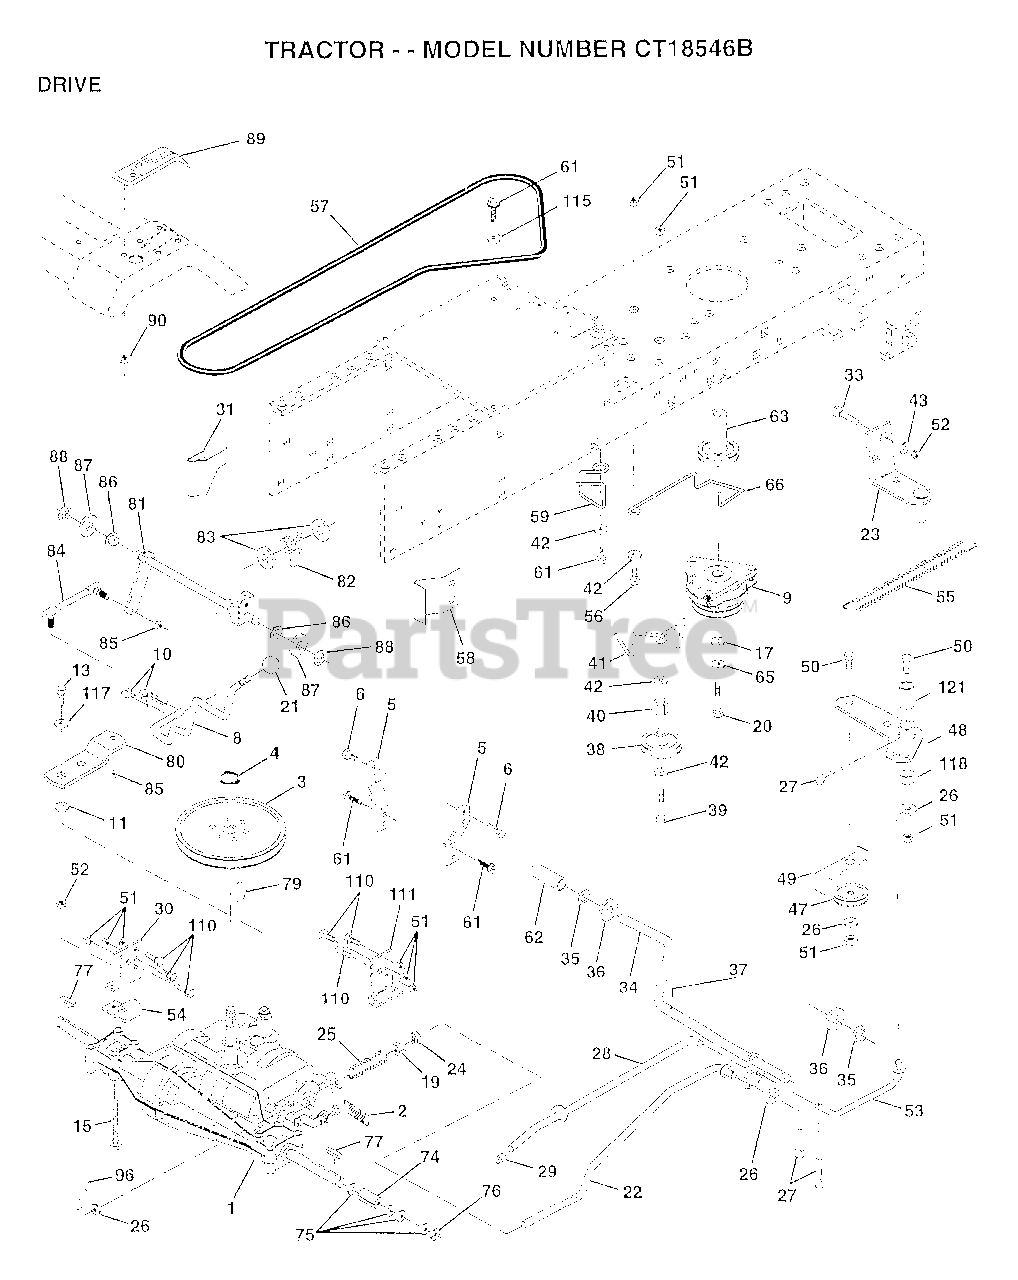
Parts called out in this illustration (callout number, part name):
1	TRANSAXLE PEERLESS
3	PULLEY TRANSAXLE
4	RING
5	STRAP TORQUE
6	SCREW
8	ROD SHIFT FEND YT
10	PIN COTTER 1/8
11	WASH-SHFT PLT LT
13	BOLT.1/4-28.W/PAT
15	BOLT.HX.FLG.5/16
17	WASHER
19	NUT
20	BOLT.7/16-20X4.25
21	KNOB T (1/2-HOLE)
22	ROD.ASM.BK.44.MWR
23	BRACKET.ASM.MTG
24	NUT
25	"SPRING,ROD BRAKE"
26	WASHER
27	COTTER PIN
28	ROD.BRAKE.PARK.LT
29	PLUNGER CAP T
30	BRKT TRANS LH
31	KEEPER BELT LH
33	BOLT
34	SHAFT ASM-PEDAL F
35	NYLON BEARING
36	WASHER LT
38	PULLEY.IDLER.FLAT
39	BOLT
40	SPACER T
41	KEEPER, IDLER
42	WASHER
43	WASHER T
48	BELLCRANK ASM
49	RETAIN BELT
53	"LINK, CLUTCH T"
54	"CLIP,INSULATOR"
55	"SPRING, RETURN LT"
57	BELT.GRDRV.94.75
58	"KEEPER,BELT RH"
59	KEEPER BELT CNTSP
61	SCREW
62	PEDAL COVER T
63	PULLEY ENGINE
65	LOCKWASHER
66	KEEPER-BELT
74	SPACER HYT
75	WASHER
76	E RING HYT
77	SQ KEY STD
80	"ARM,SHIFT"
81	"SHAFT,SHIFTER"
82	"SPRING,TORSION"
83	WASHER
84	"ROD LINK,SHIFT AD"
85	NUT.CNT.LOCK.1/4
86	BUSHING
87	WASHER D
88	KLIP RING
89	CONSOLE SHIFTER
90	NUT
96	RETAINER M
111	BRKT TRANS RH
115	WASHER GT
117	WASHER PM
118	SPACER-BELLCRANK
121	NYLINER-CLUTCHING
